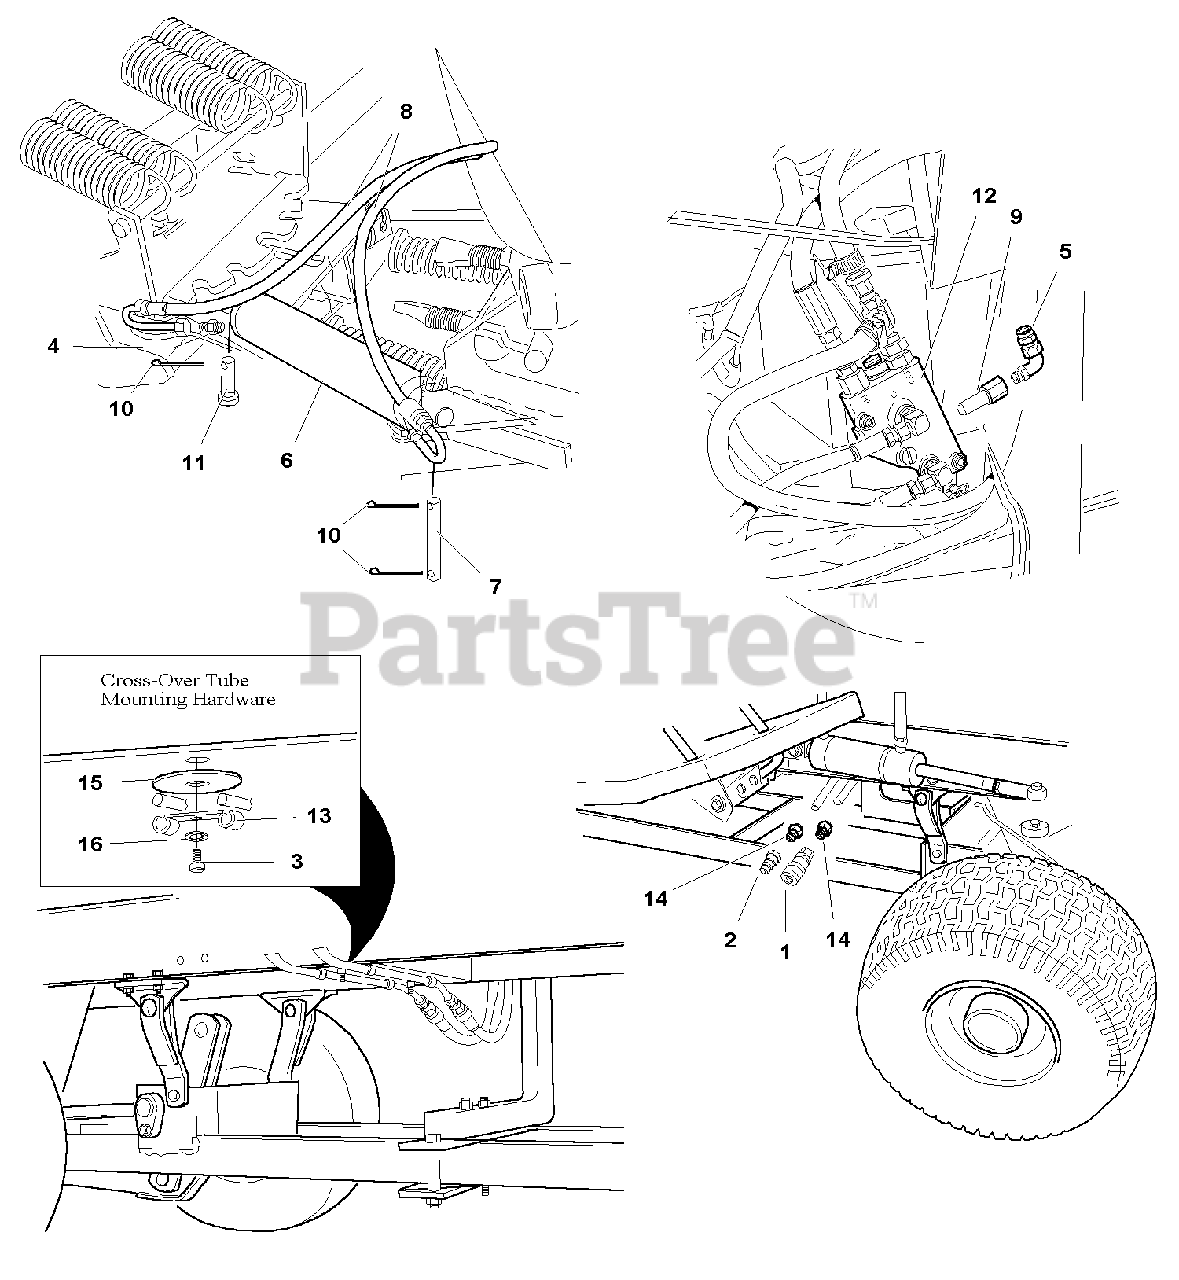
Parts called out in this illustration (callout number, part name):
1	QUICK CONNECTOR, Female Nose Piece Assembly
2	QUICK CONNECTOR, Male Nose Piece Assembly
3	CAPSCREW, Hex Washer Head, Taptite, 5/16-18 x 1
4	FITTING, Cylinder, Male
5	FITTING, Elbow
6	CYLINDER, Angling
7	PIN, Cylinder, 5/8
8	HOSE, Hydraulic, 1/2" x 28"
9	FITTING, Pressure Beyond Port
10	PIN, Cotter
12	CONTROL VALVE, Single Spool, Power Beyond
13	CLAMP, Metal Cross Over Tube Retaining
14	FITTING, Tube, Male
15	WASHER, 5/16
16	WASHER, Lock, 5/16
